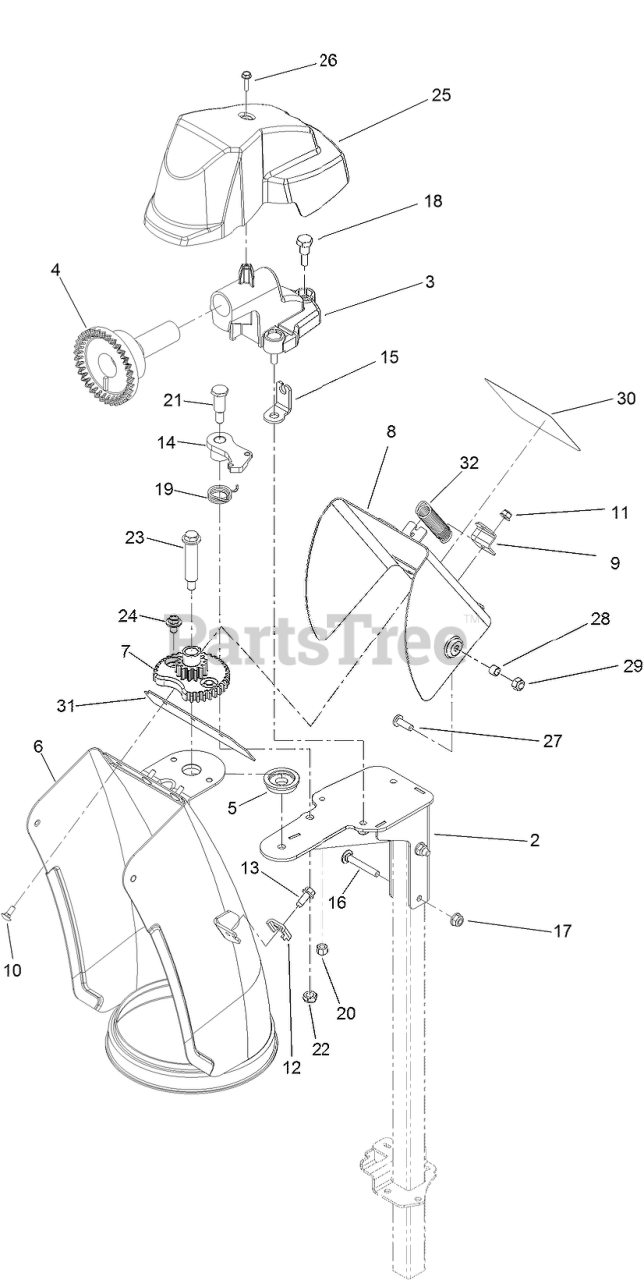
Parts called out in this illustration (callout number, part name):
2	SUPPORT-CHUTE
3	MOUNT-GEAR, FACE
4	GEAR-FACE
5	SPACER-CHUTE
6	CHUTE WELD ASM
7	GEAR-CHUTE
8	DEFLECTOR WELD ASM
9	BRACKET-SPRING
10	BOLT-CARR
11	NUT-HF
12	CLAMP-CABLE
13	SCREW-HWH
14	LATCH-CHUTE
15	ANCHOR-CABLE
16	BOLT-CARR
17	NUT-FLANGE, NI
18	SCREW-SHOULDER
19	SPRING-TORSION
20	NUT-HEX
21	SCREW-SHOULDER, HH
22	NUT-HEX
23	BOLT-SHOULDER
24	SCREW AND WASHER ASM
25	COVER-CHUTE, GEAR
26	SCREW-HWH
27	SCREW-PH
28	SPACER
29	NUT-HEX
30	DECAL-DANGER
31	GASKET-DEFLECTOR
32	SPRING-CHUTE, UPPER
